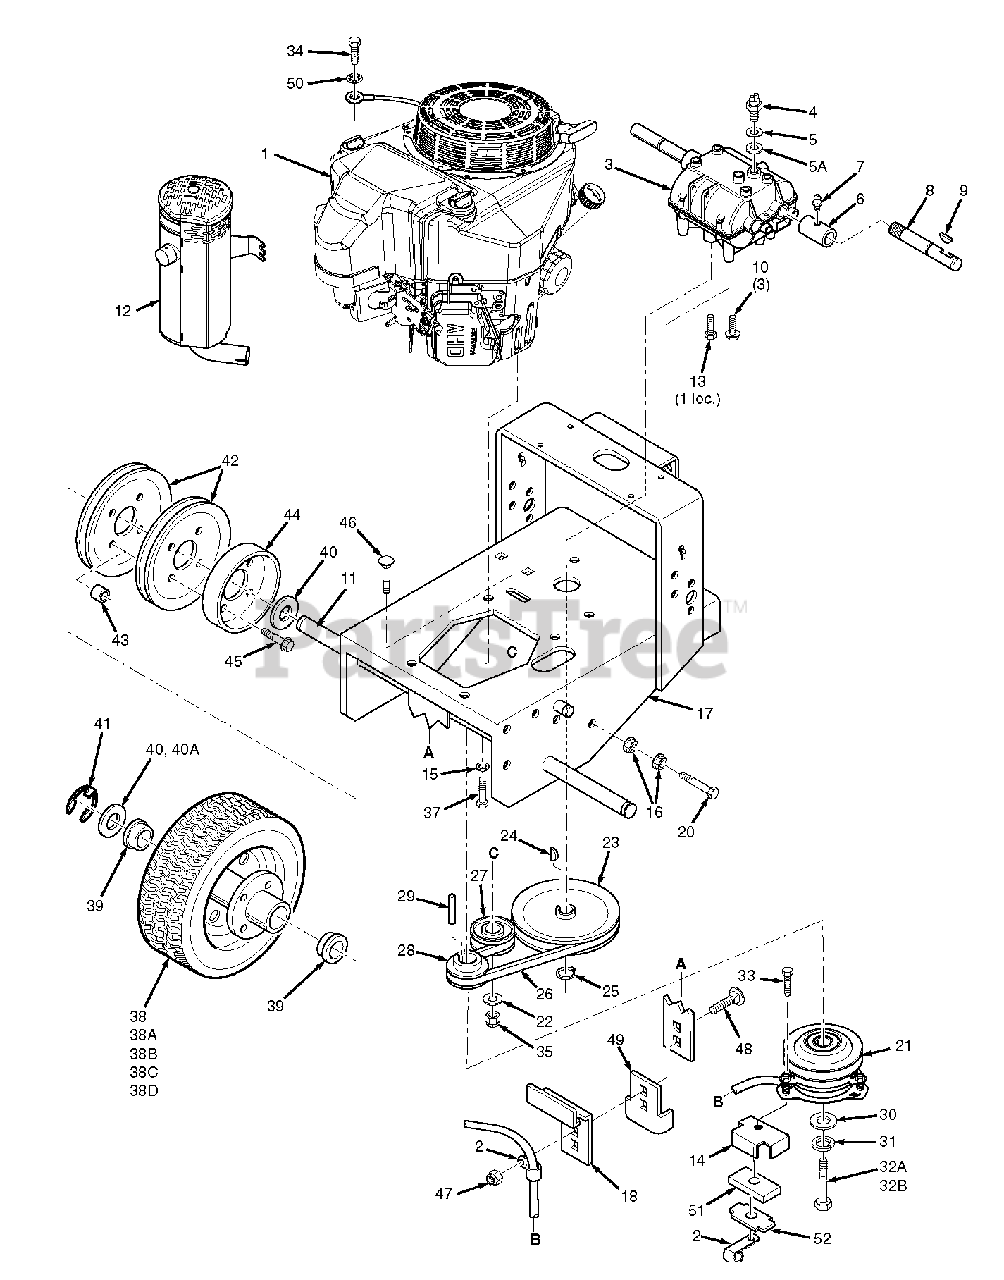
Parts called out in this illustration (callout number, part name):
1	Engine, Kawasaki FS481Z
1	Engine, Kawasaki FS541V
2	Cable Clamp
3	Transmission, 5-speed (Peerless 700-070, 9 tooth spline)
4	Neutral Safety Switch
5	Fibre Washer, thin
5A	Fibre Washer, thick
6	Coupler, Jackshaft
7	Grease Fitting, straight 1/4-28
8	Jackshaft (fits SW32,36,48& 52)
9	Key, Hi-Pro #9
10	Bolt, 5/16-18 X 3/4" Hex Head
11	Wheel Axle (SW36,48 & 52)
11	Wheel Axle (SW 32)
12	Muffler - Kawasaki
13	Bolt, 5/16-18 X 3/4" Hex Head
14	Backing Plate
15	Lock Wshr. 3/8"
16	Nut, 3/8-16 Serrated Flange
17	Engine Deck (fits SW32)
17	Engine Deck (fits SW36,48 & 52)
18	Plate, Clutch Bracket
19	Nut, 5/16-18 Serrated Flange
20	Bolt, 3/8-16 x 3-3/4" Hex Head
21	Electric Clutch (Ogura)
22	Washer, 3/8" (.391 x .938 x .105)
23	Pulley, Transmission Input
24	Key, Woodruff #9
25	Retaining Ring, 5/8" Ext, Basic
26	Belt, Transmission Drive
27	Idler Pulley, Transmission
28	Pulley, Traction Drive
29	Key, 1/4 x 1/4 x 3/4"
30	Flat Washer, 7/16" Special
31	Lock Washer, 7/16"
32A	Bolt, 7/16-20 x 2-1/2" Hex Head
32B	Cpsrw, M10-1.5 x55 Metric Hex Hd
33	Bolt, 5/16-18 x 1-3/4" Hex Head
34	Bolt, M8-1.25 x 16
35	Nut, 3/8-16 Elastic Stop
36	Flat Washer, 5/16"
37	Bolt, Hex Head 3/8-16 x 1-1/4"
38	Wheel Assembly (fits SW36,48,52)
38	Wheel Assembly (SW32)
38A	Tire, 13 x 6.50-6, 2-ply (fits SW36,48,52)
38B	Rim & Bearing Assembly
38C	Tire, 13 x 5.00-6 2-ply (SW32 only)
38D	Rim Assembly (SW32 only)
39	Wheel Bearing
40	Washer, 1-1/16 x 1-3/4 x 12 ga
40A	Washer, 1-1/16 x 1-1/2 x 18 ga
41	Retaining Ring, 1" Ext.- "E"
42	Pulley, Wheel Drive
43	Spacer, Wheel Pulley
44	Brake Drum
45	Bolt, 5/16-18 x 1-1/2" Serrated Flange
46	Bolt, 3/8-16 x 2" Carriage
47	Nut, 5/16-18 Elastic Stop
48	Bolt, 5/16-18 x 1" Carriage
49	Anti Rotation Bracket
50	Lock Washer External Tooth
51	Rubber Pad, Clutch Stop
52	Plate, Backing
